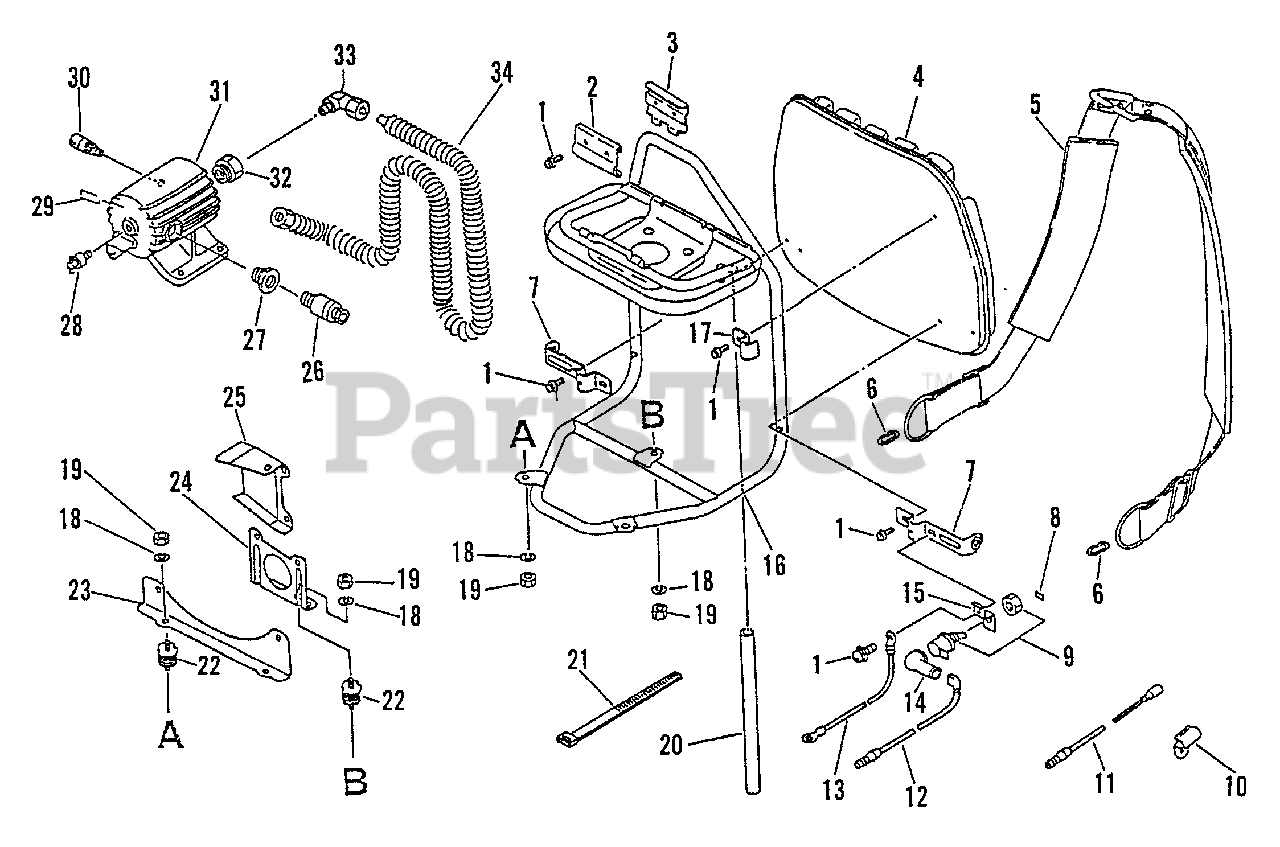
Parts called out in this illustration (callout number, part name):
1	SCREW - 5X14
2	BACKPACK STRAP ASSY
3	HARNESS ASSY
4	CUSHION, BACKPACK
5	STRAP, BACKPACK
6	RING, STRAP
7	BRACKET - LOWER
8	LABEL - SWITCH
9	IGNITION SWITCH ASSY
10	CLAMP
11	LEAD (A)
13	LEAD - GROUND
14	SLEEVE
15	BRACKET, SWITCH
16	FRAME, BACKPACK
17	BRACKET, CUSHION
18	LOCKWASHER - 5
19	NUT - 5 -- FLANGE
20	PIPE - FUEL
21	TIE, CABLE
23	BRACKET, COMPRESSOR
24	BRACKET, COMPRESSOR
25	DUCT, AIR
26	VALVE, SAFETY
27	BOLT, EYE
28	VALVE
29	LABEL - HOT SURFACE
30	CONNECTOR
31	TANK, AIR
32	BOLT, EYE
33	ELBOW, HOSE - 1/4
34	HOSE, COOLING
